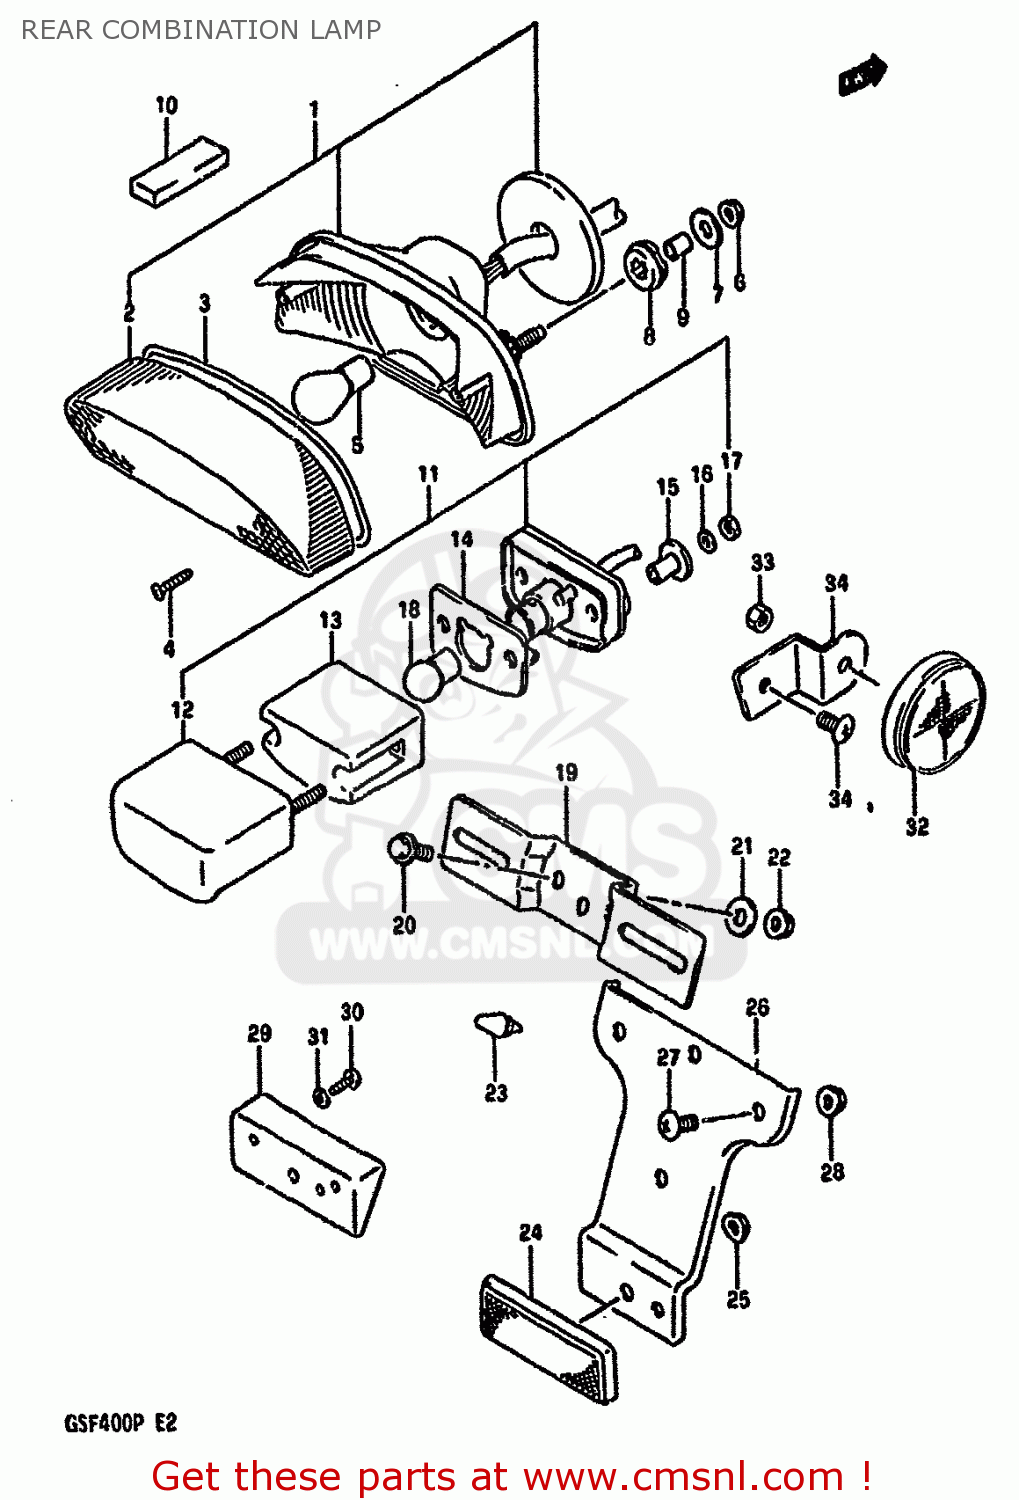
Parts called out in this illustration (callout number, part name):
1	LAMP ASSY,RR COMBINATION
2	LENS
3	GASKET (NAS)
4	SCREW
5	BULB(12V21/5W)
6	NUT
7	WASHER
8	CUSHION
9	SPACER
10	CUSHION,REAR LENS
11	LAMP ASSY,LICENSE
12	COVER,LICENSE LAMP
13	LENS
14	GASKET,LICENSE LAMP (NAS)
15	SPACER
16	WASHER,LOCK 4M
17	NUT
18	BULB
19	BRACKET,LICENSE PLATE
20	BOLT
21	WASHER,COVER,FRONT
22	NUT
23	CUSHION
24	REFLECTOR ASSEMBLY,REAR
25	NUT 5MM
26	BRACKET,REAR REFLECTOR
27	SCREW 6X12
28	NUT
29	SPACER,RR RR
30	SCREW
31	WASHER
32	REFLEX REFLECTOR,RR
33	NUT
34	BRACKET,REAR SIDE REFLECTOR
35	SCREW
